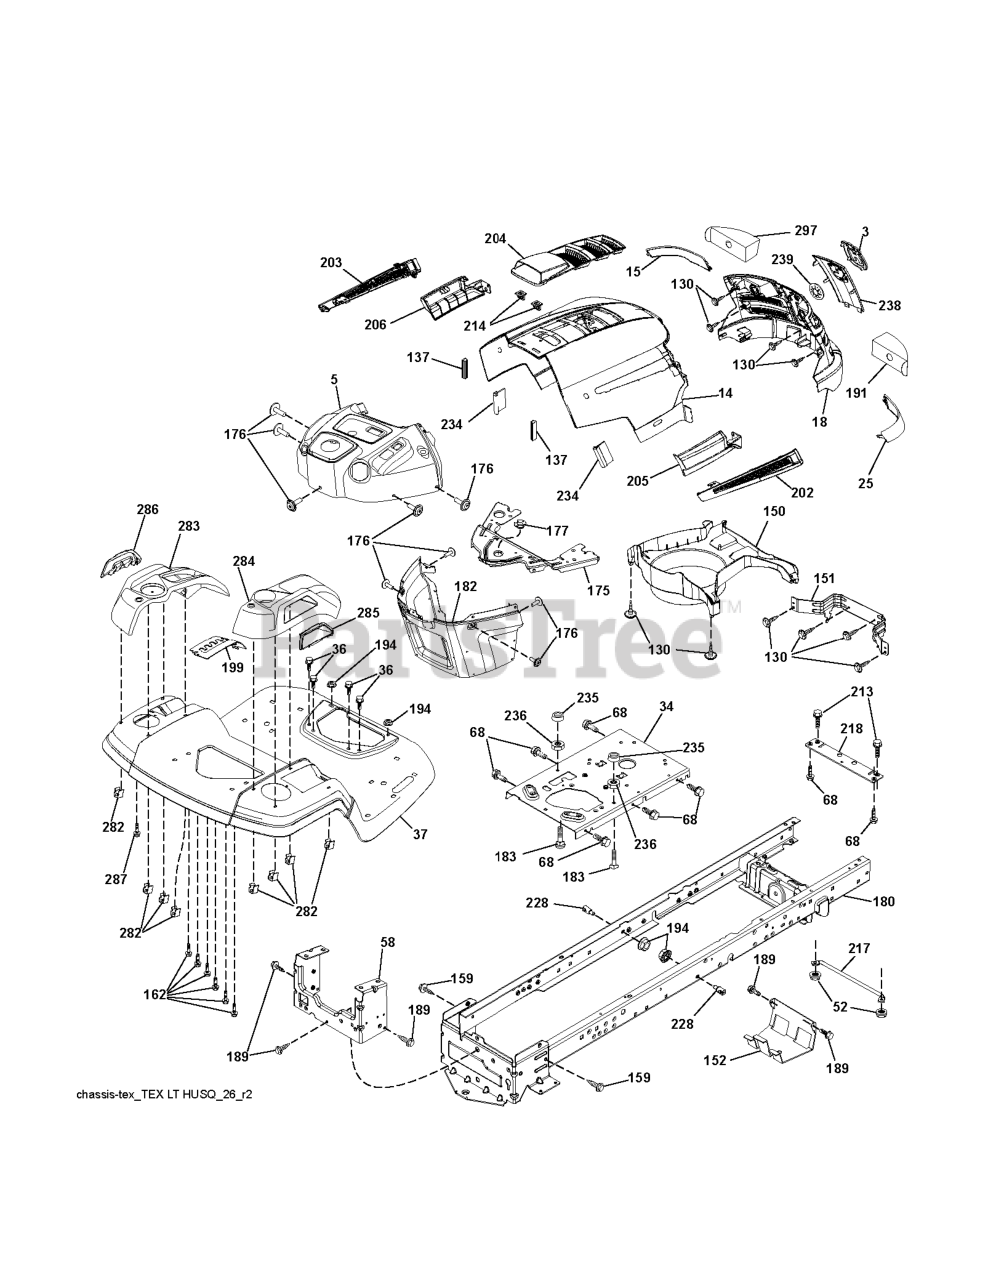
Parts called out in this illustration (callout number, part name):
3	RP LOGO
5	DASH
14	HOOD
15	LENS.HUSQVARNA LT.LH
18	GRILLE.SVC.HUSQVARNA.LT.GREY
25	LENS.HUSQVARNA LT.RH
34	PLATE.ENGINE.WELDED.CHASSIS
36	SCREW 5/16"
37	RP FENDER.TLT.FS.W/CPH.422
52	LOCKNUT
58	DRAWBAR UPPER 2PC SMALL FENDER
68	Screw 5/16-18 x 1/2 Hex, Self Tapping 5/16-18 x 1/2
130	SCREW.#10 X 0.750.BOS
137	BUMPER DASH
151	BRACKET PIVOT
152	SHIELD.BROWNING.W/TEX
159	SCREW, 3/8-16X3/4
162	SCREW.HI-LO.CONSOLE
175	CROSSMEMBER
176	SCREW.#10-24X5/8.RN.QU
177	BUSHING STEERING
180	CHASS.WLDMNT.TL.12GA/2P.48/54
182	DASH.LOWER.PREDATOR LT
183	BOLT.5/16-18X1-1/4 FULL THD
189	SCREW
191	INSERT.REFLECTIVE.RH.
194	NUT LOCK HEX FLANGE 5/16-18
199	PLATE.DECK.LIFT.HUSQ.LT
202	VENT SIDE HOOD LH
203	VENT SIDE HOOD RH
204	VENT TOP HOOD
205	SKIRT SIDE RH
206	SKIRT SIDE LH
213	BOLT
214	CLIP.RETAINER.TINNER.
217	ROD.PIVOT.HOOD
218	X-PIECE.HOOD.STOP.NON/
228	STUD.FASTNER.W/ANTI-ROTATE
234	BUMPER.HOOD.TEX.HUSQVARNA
235	SPACER FENDER
236	NUT.CENTERLOCK.5/16-
238	TRIM
282	CLIP.RETAINER.CONSOLE.LT.HUSQ
283	CONSOLE.DECK.LIFT.HUSQ.N/FR.GR
285	CONSOLE INSERT RH
286	CONSOLE.INSRT.LH.HUSQ.LT.BLACK
287	SCREW 1/4X20
297	INSERT REFLECTIVE
